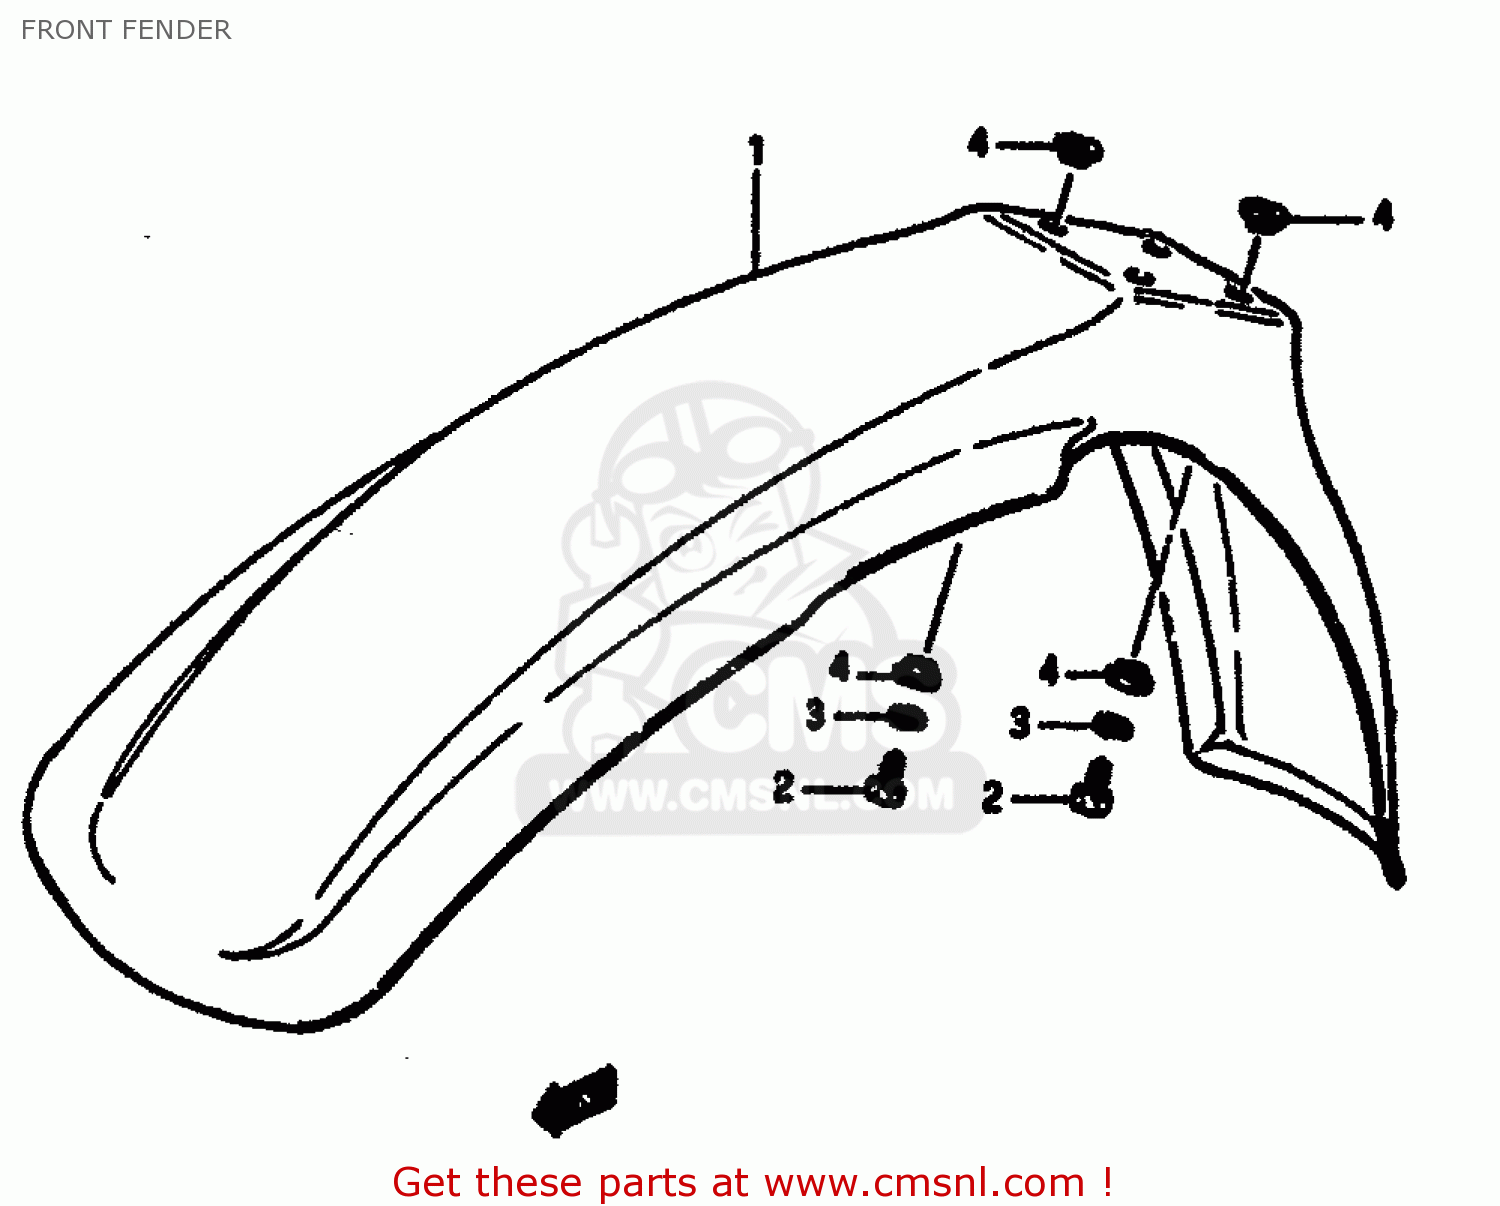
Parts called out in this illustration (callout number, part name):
1	FENDER,FRONT
2	BOLT, UPPER
3	LOCK WASHER
4	SPACER
